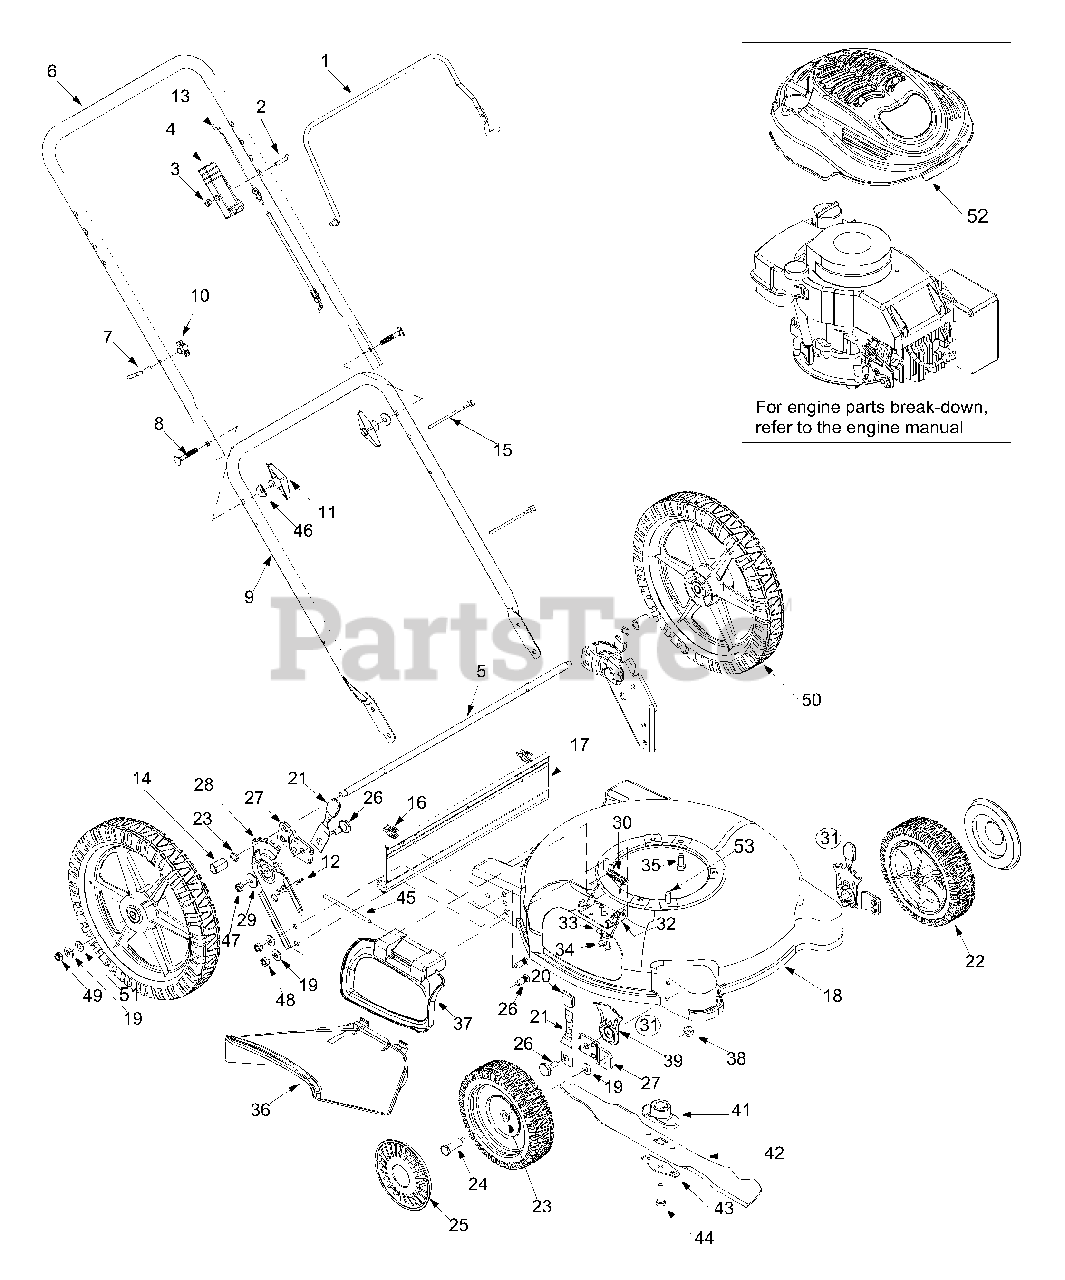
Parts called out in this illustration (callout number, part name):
2	Oval C-Sunk Screw
3	Hex Lock Nut
4	Control Housing
5	Rear Axle
8	Carriage Bolt
10	Wing Nut
11	Hand Knob
12	Hairpin Clip
13	Control Cable 55"
14	Spacer
15	Cable Tie
16	Hinge Clip
17	Trail Shield
20	Knob: Height Adjustment
21	Lever: Spring
22	Front Wheel Assy. 8 x 2.125"
23	Wave Washer
24	Axle Bolt: Front
25	Hubcap: Radial Spoke, Yellow
26	Shoulder Bolt .5" dia. x .357"
30	Torsion Spring
31	Height Adjust. Assembly RH
33	Bell Washer
34	Hex Washer Hd. TT Screw
35	TT Sems Screw
36	Chute Deflector
37	Mulching Plug Assembly
38	Hex Lock Nut
39	Height Adjustment Plate
41	Blade Adapter
42	20" Mulching Blade
43	Blade Bell Support
44	Hex Bolt
45	Hinge Pin
46	Saddle Washer
47	Lock Nut
48	Hex Nut 3/8-24
49	Lock Nut
50	Rear Wheel 14 x 2.125"
51	Flat Washer
52	Engine Shroud
53	Hex Bolt #10-32 x 0.30"
